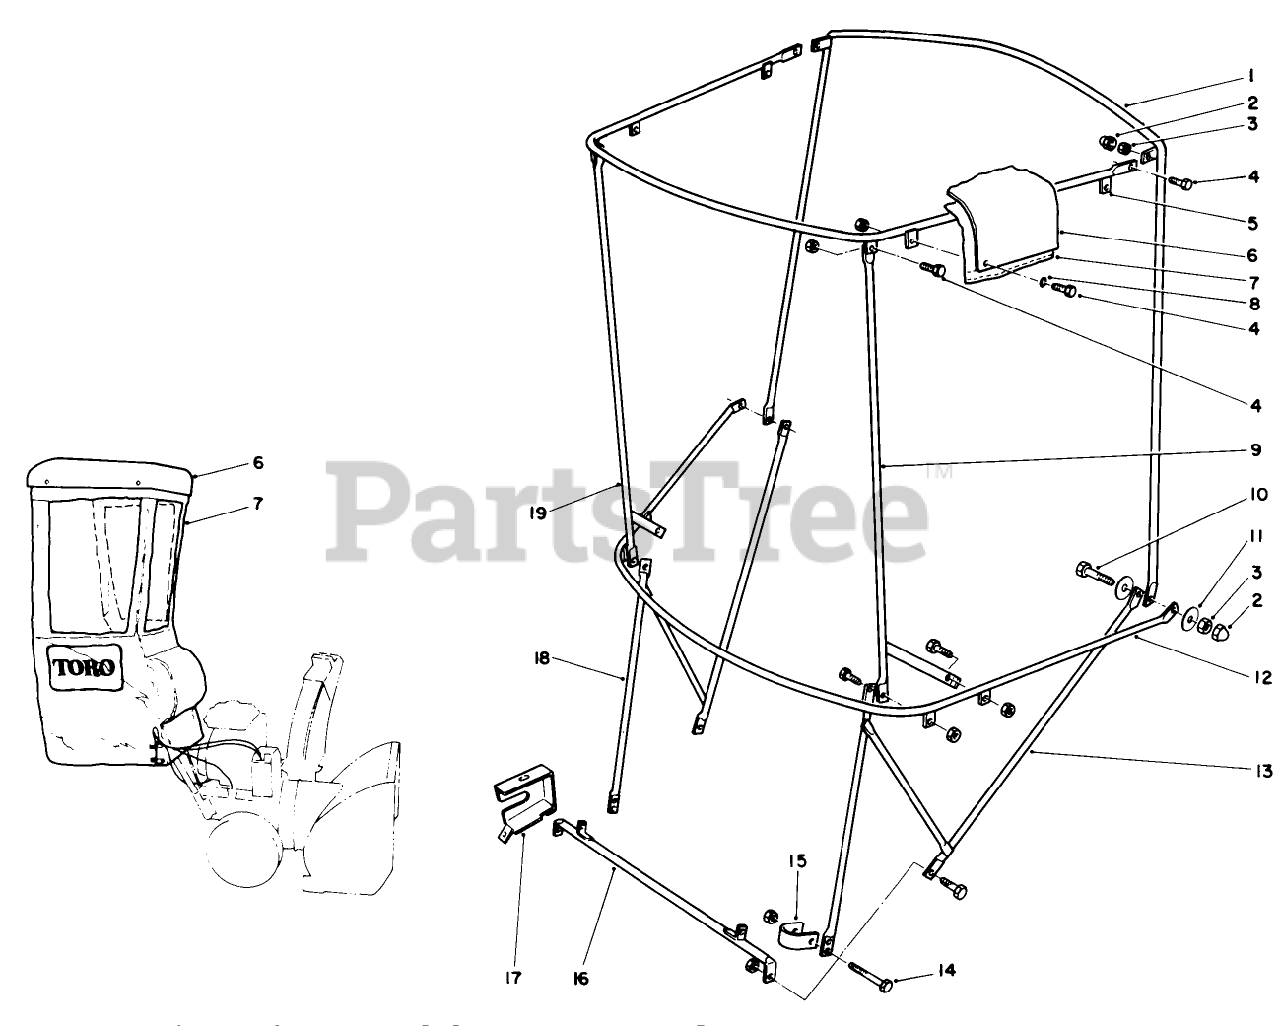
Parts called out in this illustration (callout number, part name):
3	NUT-HEX, SIDE DEFORM
4	SCREW-HH
6	Top-Plastic
7	Cover-Vinyl
8	WASHER-FLAT
10	SCREW-HH
14	SCREW-HH
15	CLAMP
18	RH BRACKET
